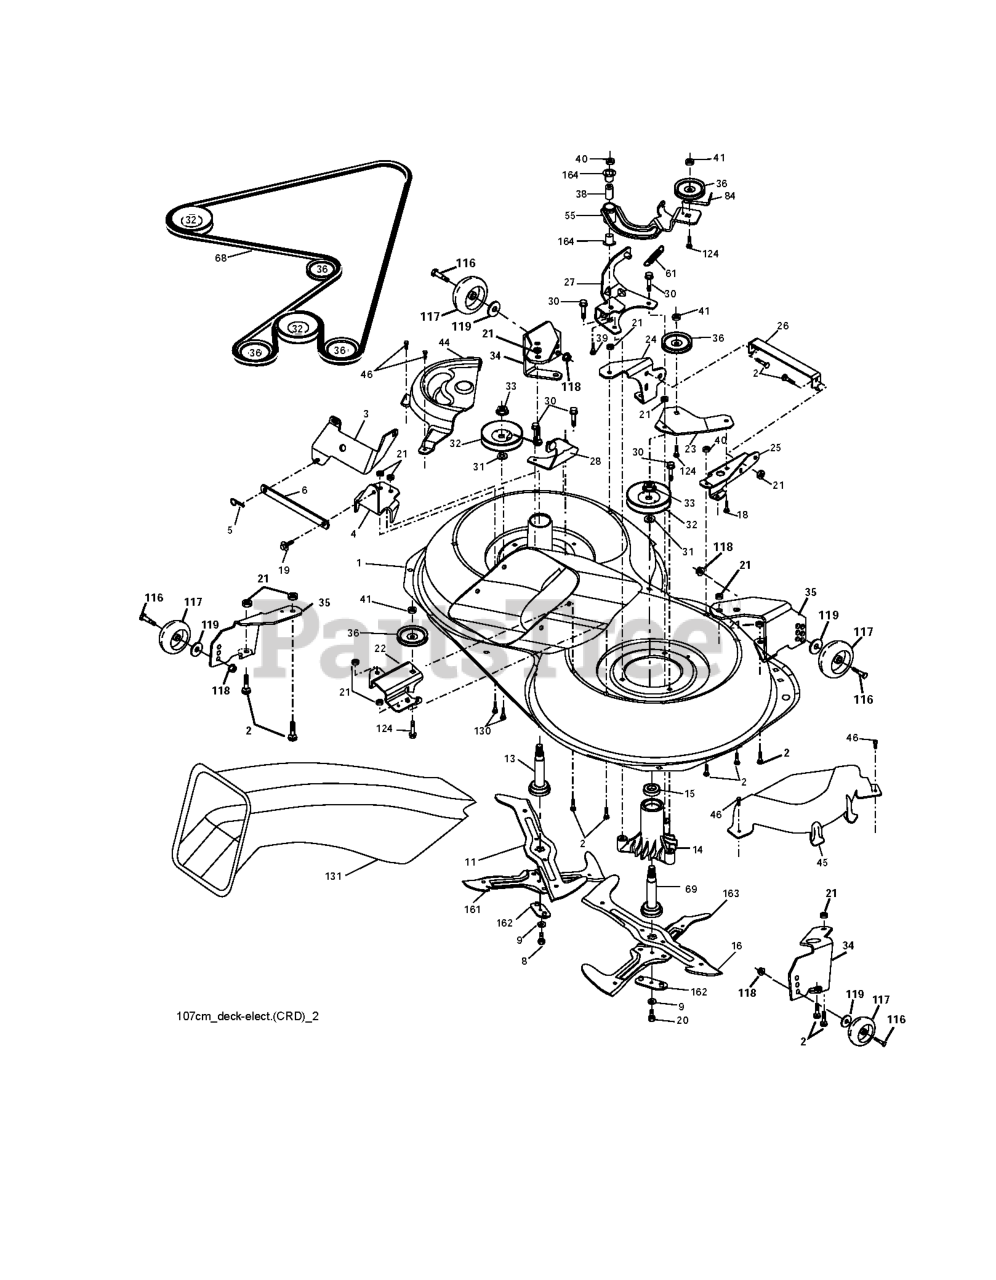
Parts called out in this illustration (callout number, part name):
1	Housing Asm. Mower 107 CRD
2	RP BOLT 5/16-18 X3/4 ZN/YEL GR
5	RETAINER-SPRNG RB
6	BAR.SWAY.92.CRD
8	BOLT.3/8-24X1.25 GR8
9	LOCKWASHER
11	BLADE.3N1.LH.CRD
13	SHAFT ASM VENT
14	HOUSING.MANDREL.VENTED (MACHD)
16	BLADE.3N1.RH.CRD
19	BOLT SHD 5/16-18
20	BOLT.3/8-24X1.25GR8. LHTHRD
21	LOCKNUT
22	BRACKET.IDLER.RR.107.CRD
25	BRACKET RF
26	SUPPORT
28	BRACKET
30	SCREW, WASHER HEAD
31	WASHER.SPACER.MANDREL
33	NUT.FLANGE.LOCK.TOP
34	BRACKET
35	BRACKET
36	PULLEY.IDLER.4.25
41	NUT LOCK FLG 3/8-16 UNC
45	COVER.MANDREL.RH.CRD
46	SCREW.1/4-20X5/8
55	ARM.IDLER.107.CRD
68	HEX-BELT 107 MOWER
69	SHAFT.ASM.W/LWR.BRG.RH.THREAD
84	KEEPER, BELT IDLER
116	SHOULDER BOLT
117	RP WHEEL. GUAGE RALLY
118	LOCKNUT
119	WASHER.5/16.FLAT.STE.STD.
124	BOLT.3/8-16X1.50
130	BOLT.CARR.SQNK.5/16-18UNC.X3/4
131	CHUTE BAGGER
163	BLADE.CROSS.RH.CRD.107
164	BRNG T
